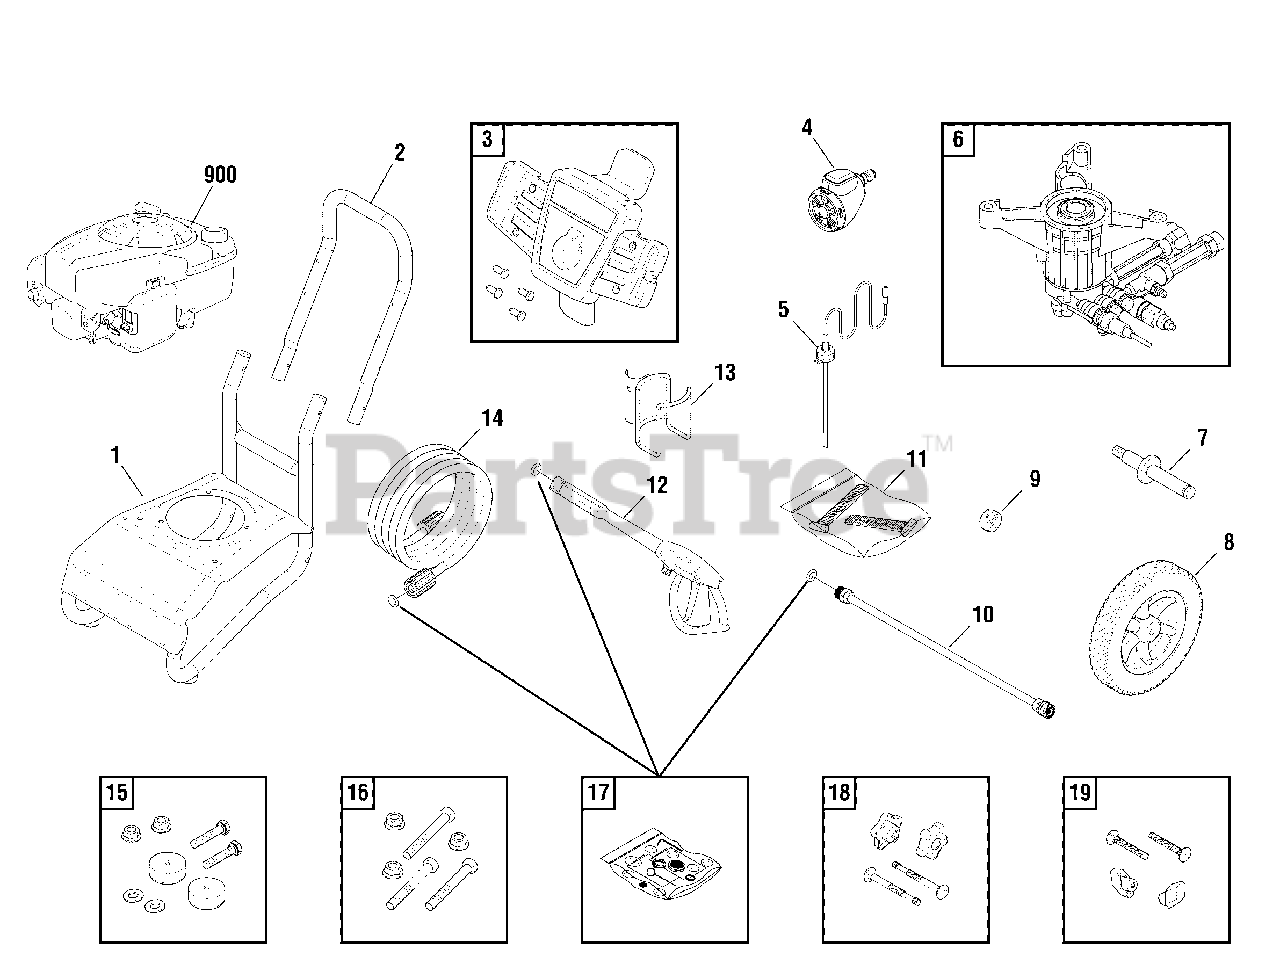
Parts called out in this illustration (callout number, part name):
10	EXTENSION-QC
12	GUN
14	HOSE
15	MOUNT-VIBRATION
16	KIT-HARDWARE PUMP MOUNTING
900	** ENGINE
